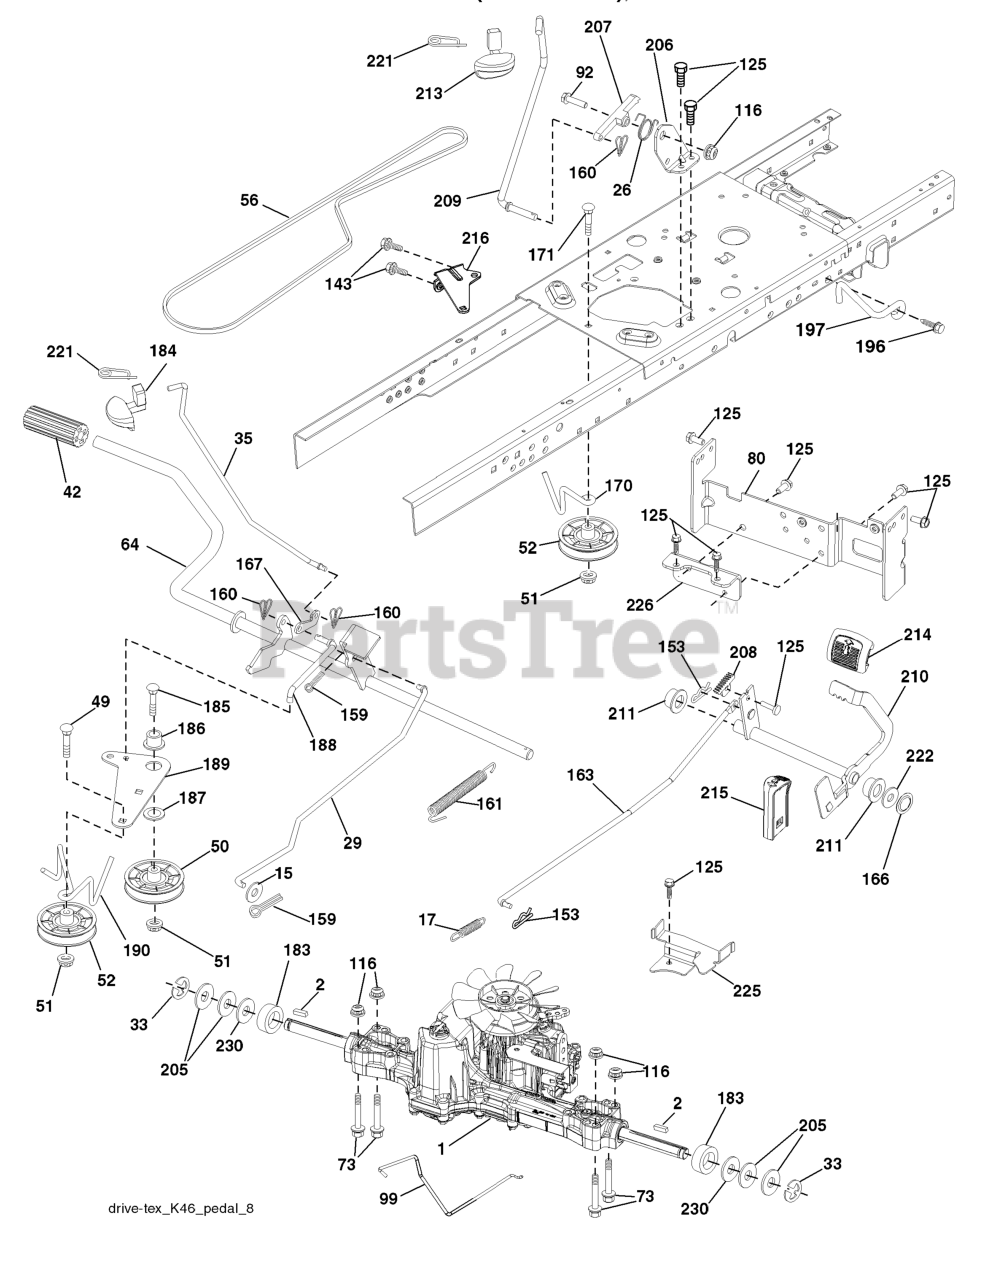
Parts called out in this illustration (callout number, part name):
1	TRANSAXLE, TUFFTORQ K46
2	SQUARE KEY
15	WASHER
17	SPRING.BRAKE.K46.GREEN
26	SPRING.RETURN.CRUISE
29	ROD.BRAKE.K46
35	ROD.BRAKE.PARKING.GT.H
42	PEDAL COVER T
50	IDLER.FLAT.910.OFFSET
51	NUT LOCK FLG 3/8-16 UNC
52	IDLER.V-GROOVE.910.OFFSET
56	V-BELT.MOWER.92.40.42/K46
64	SHAFT.ASM.PEDAL.BRK.CNTR
73	BOLT HEX 5/16-18 GR 5
80	STRAP TORQUE
92	BOLT
99	ROD.SPRING.BYPASS.K46.LT.Z
116	NUT LOCK HEX FLANGE 5/16-18
125	SCREW
143	Screw 5/16-18 x 1/2
153	RETAINER M
159	COTTER PIN
160	RETAINER CLIP
161	Spring, Return, Clutch
163	ROD.CONTROL.PEDAL.K46
166	NUT.PUSH.625.2006
167	LATCH.BRAKE.SPRING
170	KEEPER.V-IDLER.CENTER.
171	BOLT
183	SPACER AXLE
184	HANDLE.PARKG.BRK.HUSQ X667
185	BOLT
186	SPACER.RETAINER
187	WASHER 12/32X2X10GA
188	RP.LINK.CLUTCH.GROUND.DRIVE
189	BELLCRANK.GROUND.DRIVE.TEX.
190	KEEPER.BELLCRANK.DRIVE
196	SCREW 3/8-16X1
197	LINK.CLUTCH.ANIT-ROTAT
206	BRKT.MOUNT.LATCH.CRUIS
207	LATCH.CONTROL.CRUISE
208	GEAR.SECTOR.CONTROL.CR
209	ROD.CONTROL.CRUISE.GT.
210	ROCKER.ASM.PEDAL.CONTR
211	BEARING.NYLON
213	KNOB.CONTROL.CRUSIE.HU
214	PEDAL.FORWARD.HUSQVARNA.DEALER
215	PEDAL.REVERSE.TEX.GT.4
216	BRACKET.PULLEY.IDLER.W/TEX
221	RETAINER.SPRING.CLIP.H
222	WASHER 21/32 X 1-1/4 X 10 GA.
225	KEEPER.BELT.TRANSAXLE.K46
226	BRACKET.MOUNT.TORQUE.K46.TLT
230	WASHER.HARDENED
